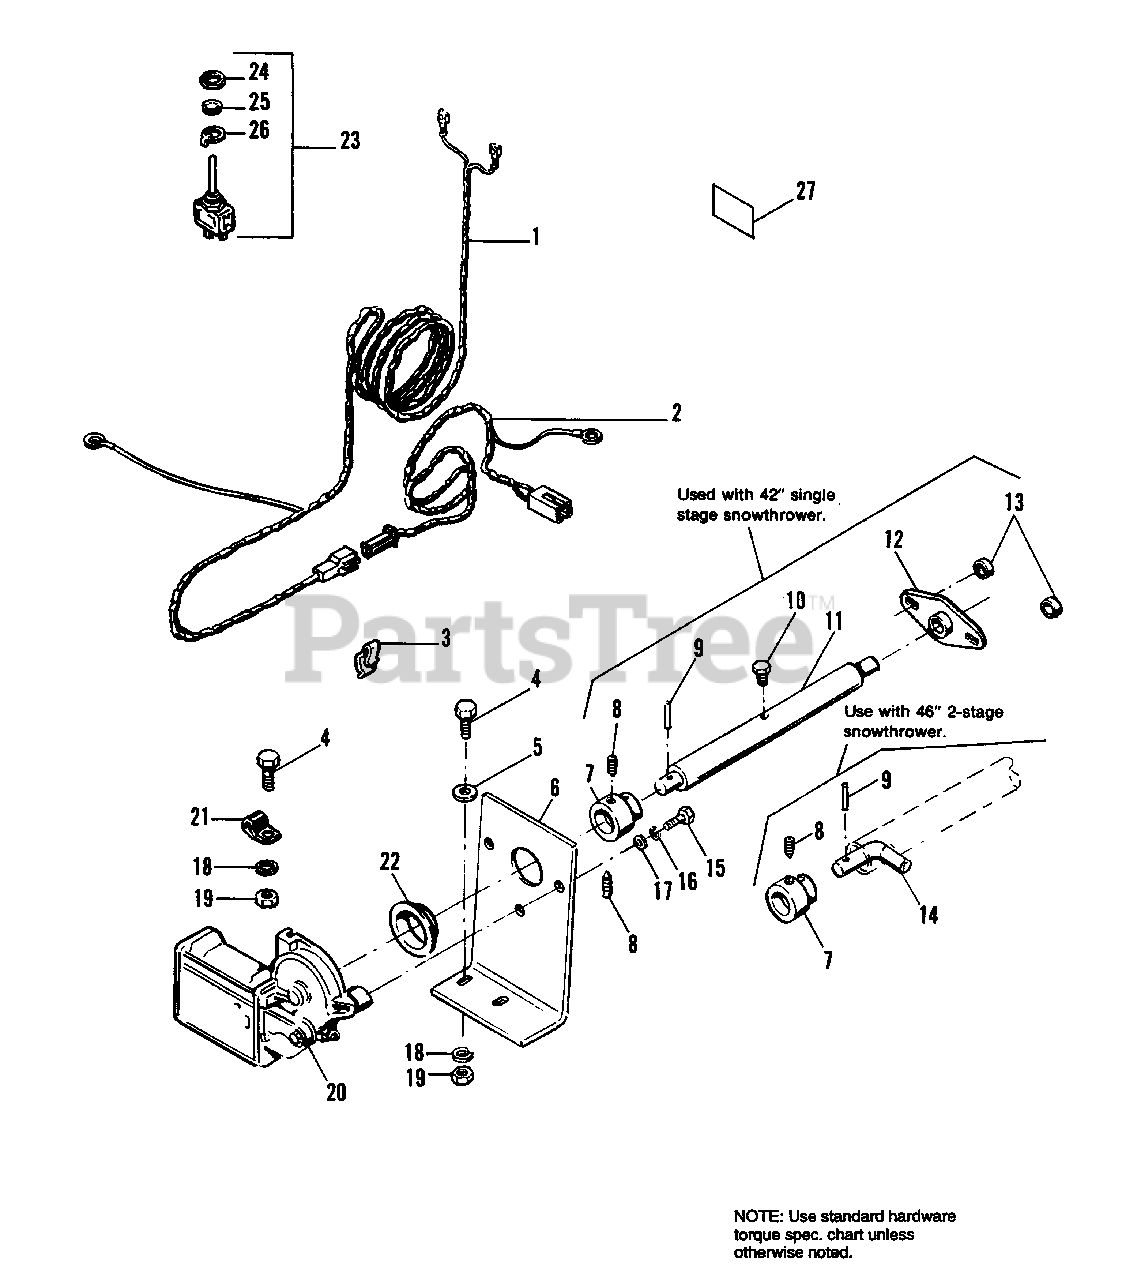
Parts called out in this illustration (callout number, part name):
1	HARNESS, Wiring, Spout Switch
2	HARNESS, Wiring, Spout Motor
3	CLIP, Cable
4	CAPSCREW, Hex Hd., 3/8-16 x 13
5	WASHER, Plain, 13/32
6	BRACKET, Motor
8	SCREW, Hex Skt. Hd. Taptite, 1/4-2 x 3/8
9	PIN, Spring 5/32 Dia. x 1 Lg.
10	SCREW, Hex Washer Hd. Taptite, 1/4-2 x 3/8
11	ROD, Spout Control
12	BEARING, Self Aligning
13	SPACER
14	Pin, Spout Control Rod
15	CAPSCREW, Hex Hd., 1/4-2 x 3/4
16	LOCKWASHER, Spring, 1/4
17	WASHER, Plain, 9/32
18	LOCKWASHER, Spring, 3/8
19	NUT, Hex, 3/8-16
20	MOTOR, Spout Control
22	BEARING, Flange
23	SWITCH, Spout Control
25	LOCKWASHER, Int. Th.
26	RING, Locking
27	DECAL, Spout Rotator
